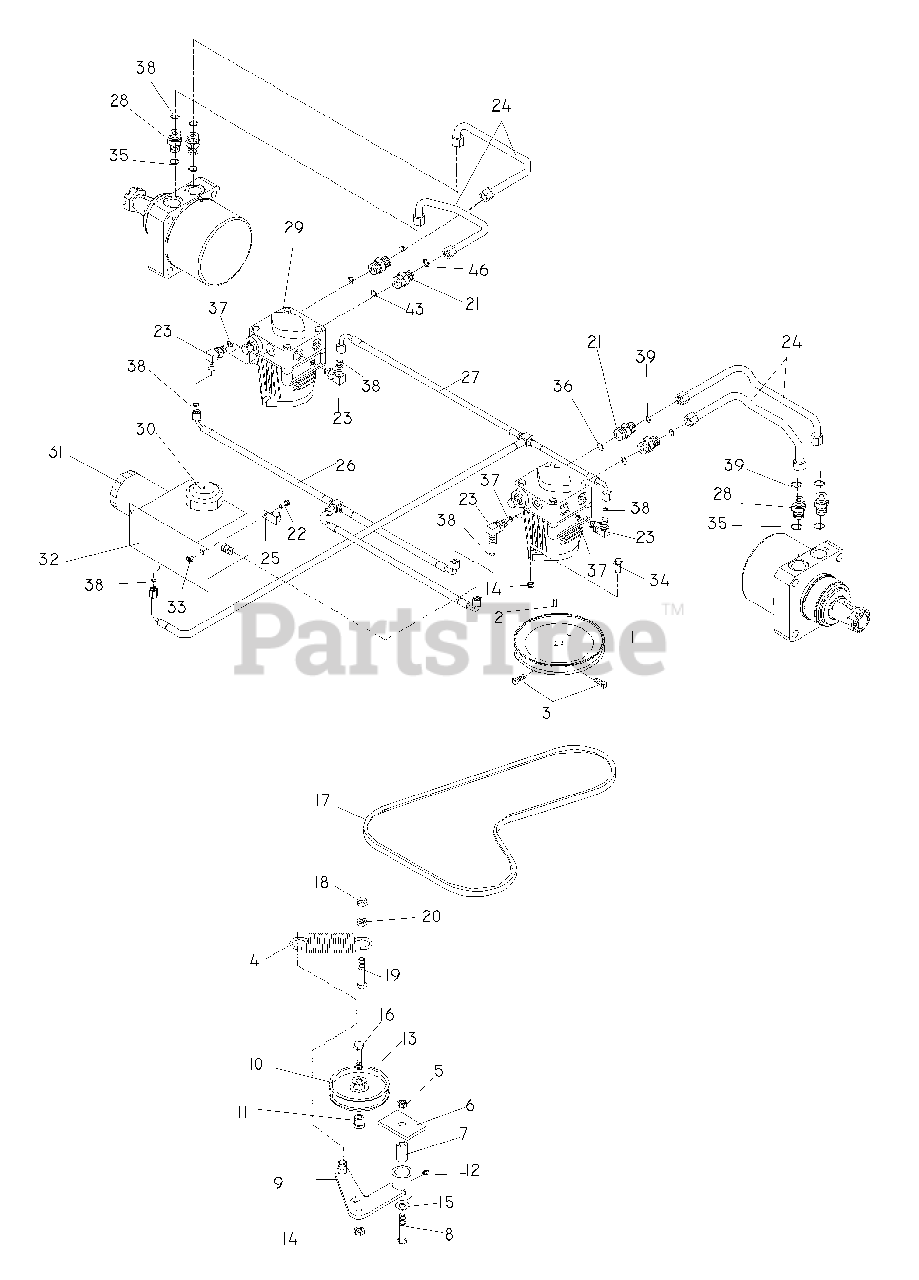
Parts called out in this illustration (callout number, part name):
2	KEY 5 MM SQ X 25 MM
3	SCREW 5/16C X 5/8 SQ HEAD
5	NUT 1/2-13 HEX NYLOC ZD
7	PIVOT BUSHING
8	HCS 1/2C X 3 1/4
9	IDLER ARM WLDT
10	IDLER PULLEY
11	BUSHING, IDLER FLANGE
12	ZERK
13	WASHER 3/8 FLAT
14	NUT 3/8C CENTERBLOCK
15	WASHER 1/2 FLAT
16	HCS 3/8-16 X 1 3/4 GR5
17	PUMP BELT
18	NUT 3/8-16 NYLOC
19	HCS 3/8C X 2
20	NUT 3/8C WHIZ
21	FITTING, STRAIGHT F6400-8-8-0
22	HCS 5/16C X 3/4
23	ELBOW, F6801-6-6-0 90 DEGREE
24	HYDRAULIC HOSE
25	LOOM CLIP
26	T-ASSEMBLY
27	T-ASSEMBLY
28	FITTING
29	HG_PUMP, 10CC W/O FAN
30	HYDRAULIC CAP
31	HYDRAULIC OIL FILTER
32	RESERVOIR W/CAP & FILTER
33	NUT 5/16 NYLOC
34	HCS 3/8C X 1 SERRATED HEAD
